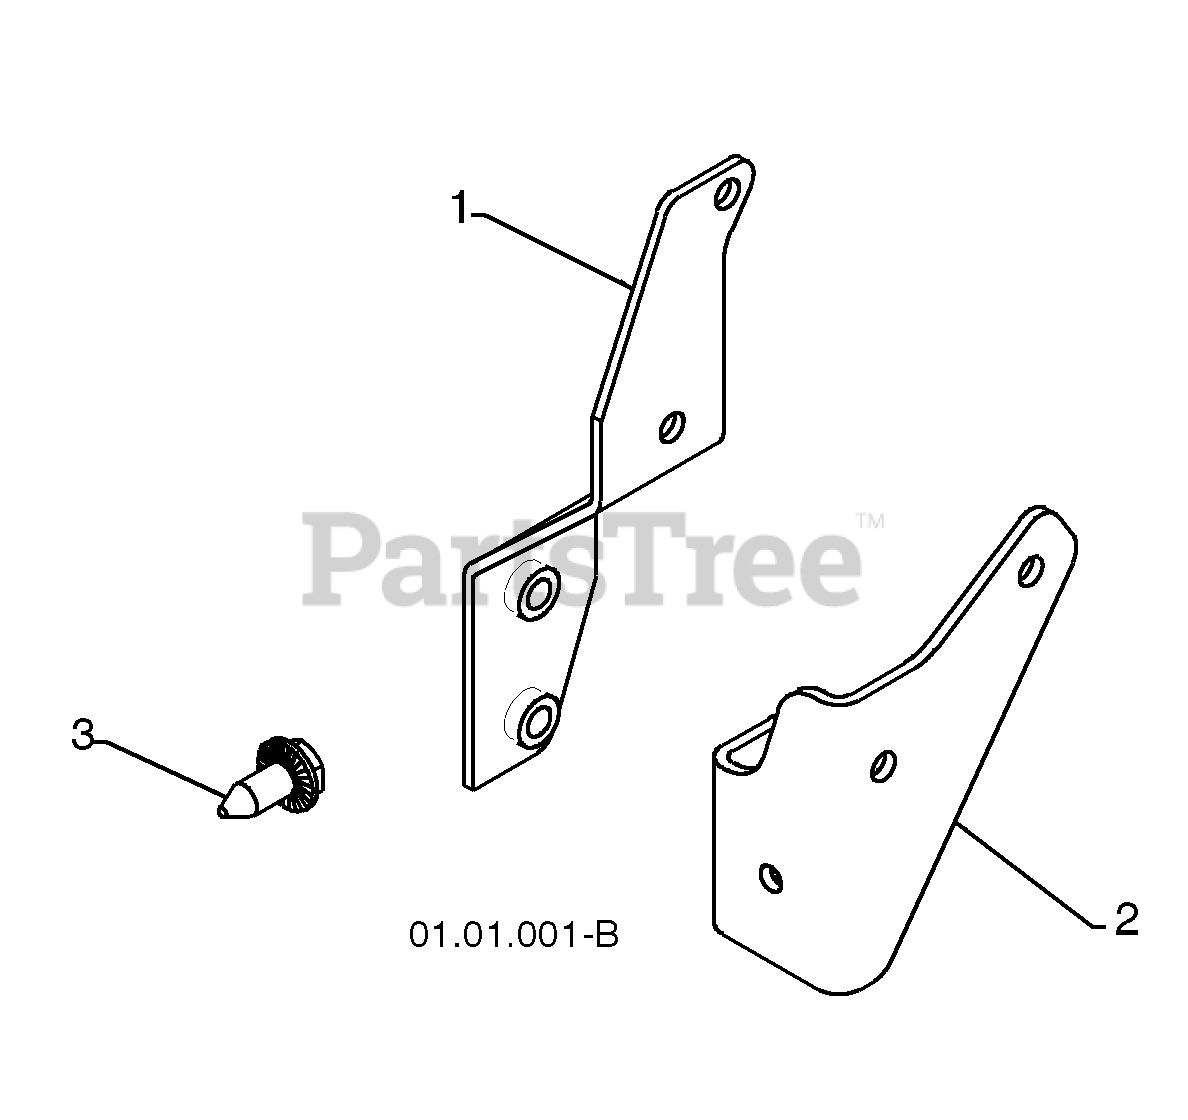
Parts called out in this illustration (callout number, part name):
1	TORQUE STRAP
2	ANTI ROTATE BRACKET
3	SCREW 5/16-18 X .750
